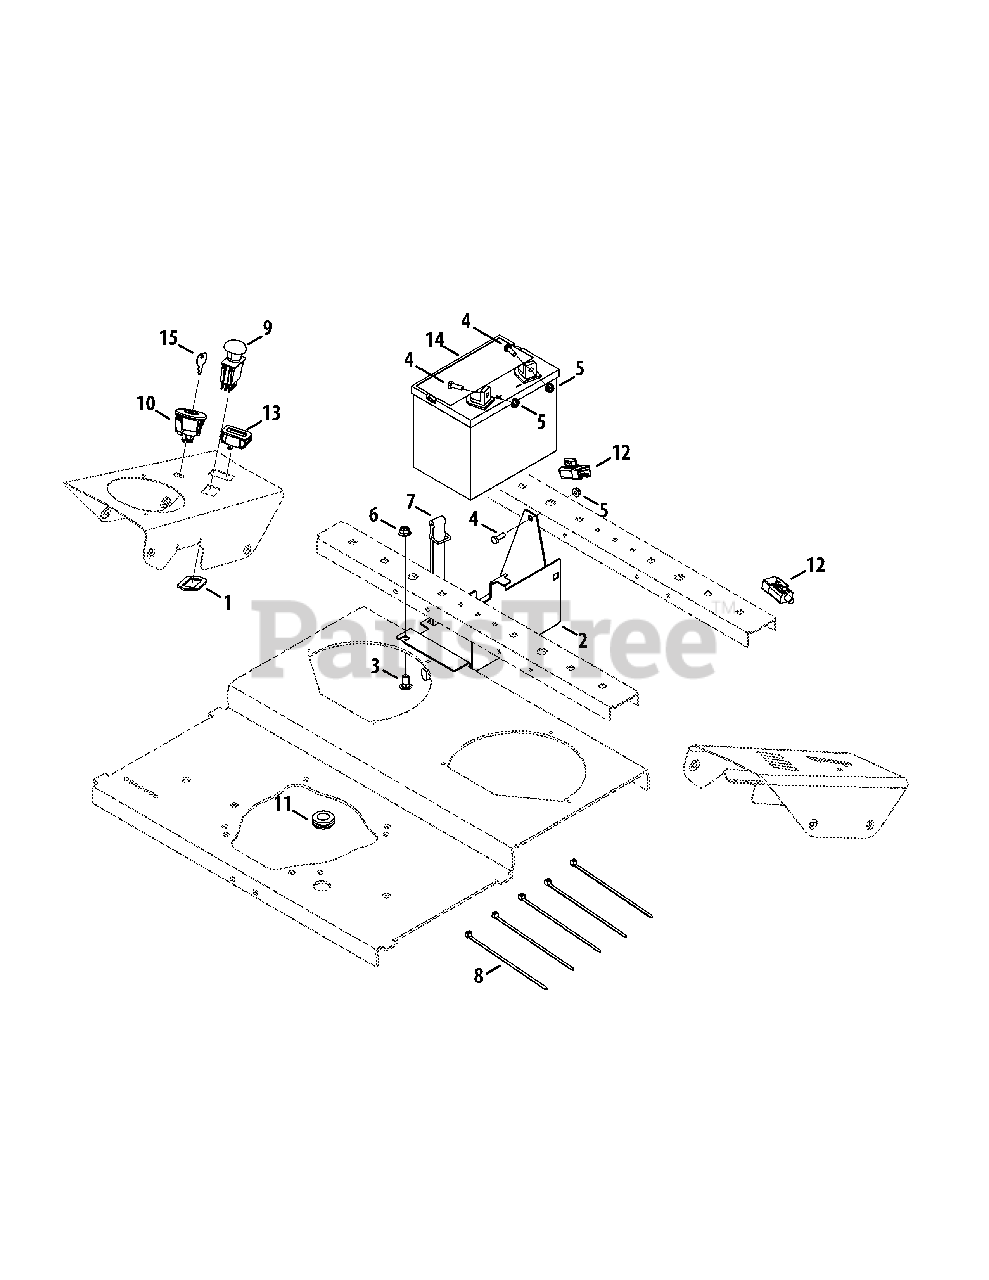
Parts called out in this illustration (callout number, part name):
1	PTO Switch Bracket
2	Battery Bracket
3	Carriage Bolt, 3/8-16 x .750
4	Hex Cap Screw, 1/4-20 x .75
5	Nut, 1/4-20, Flangelock
6	Nut, 3/8-16, Flangelock
7	Battery Strap
8	Cable Tie
9	Electric PTO Switch
10	Key Switch
11	Rubber Grommet, .75 x 1.062 x .50
12	Plunger Switch, NO/NC
13	Hour Meter
15	Key, Assembly
